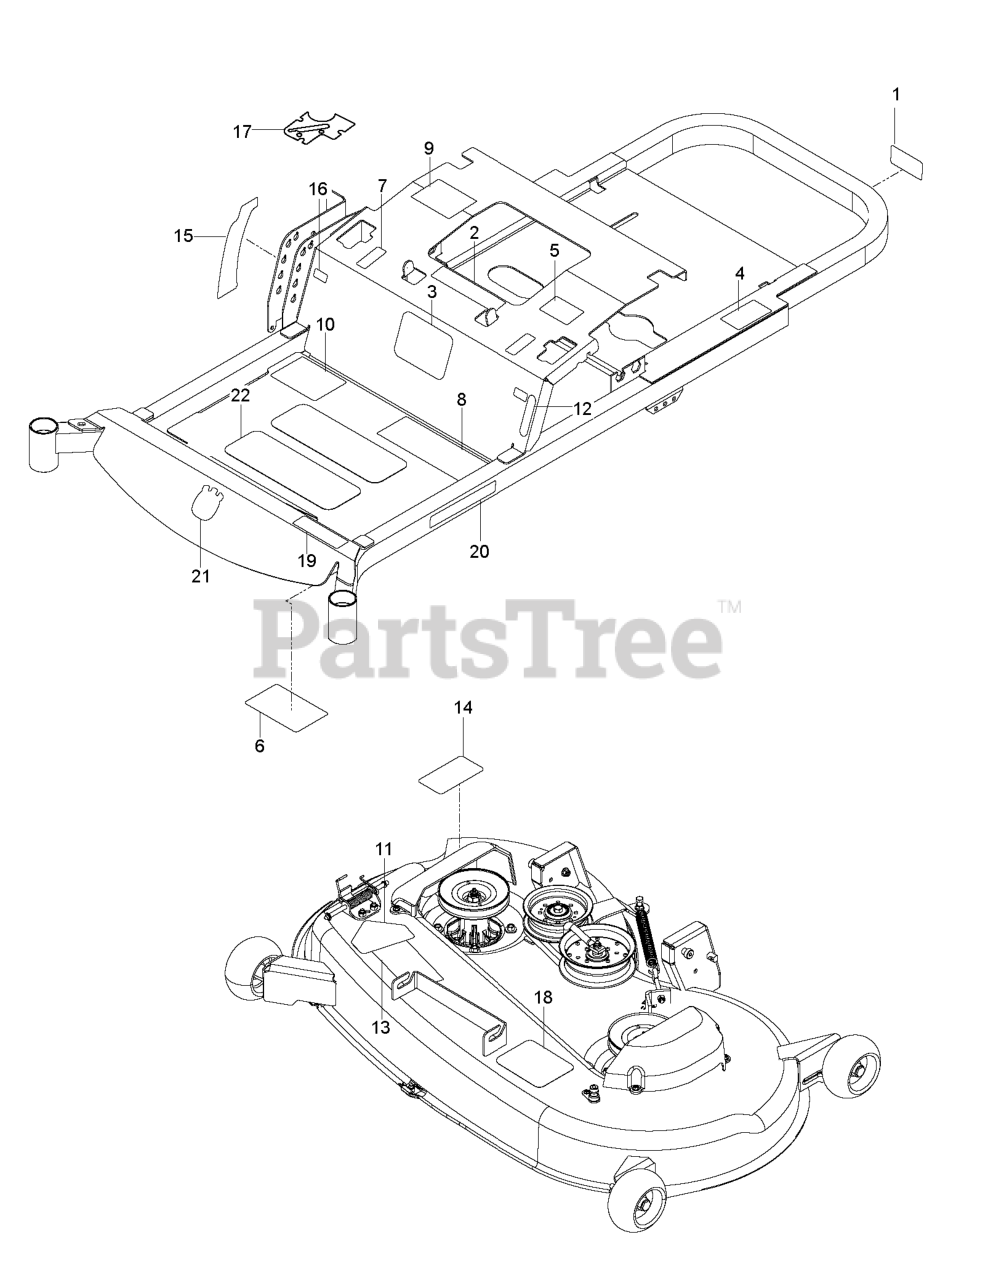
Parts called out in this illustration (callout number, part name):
1	DECAL, PROP. 65
2	EURO DECAL-BATTERY WARNIN6
3	DECAL, START
4	DECAL, DO NOT TOW
5	DECAL, EXITING MOWER
6	DECAL, SERVICE
7	DECAL, MOTION CONTROL
8	DECAL, SAFETY WARNING
9	DECAL, CUSTOMER RESPNSIBILITY
10	DECAL, WARNING
11	DECAL, CPSC
12	DECAL, PARK BRAKE
13	DECAL, EURO SEVERING
14	DECAL, CAUTION
15	DECAL, HEIGHT
16	DECAL, F.S.T.
17	DECAL, CTRL PANEL HUS WO CHOKE
18	DECAL, BELT ROUTING
19	DECAL, RZ4621 (BF UNIT)
20	RP.DECAL.BADGE.170MM.TEXTLOGO
21	DECAL.AUGER.HUSQ.CROWN.SNOW
22	ANTI-SKID PAD
